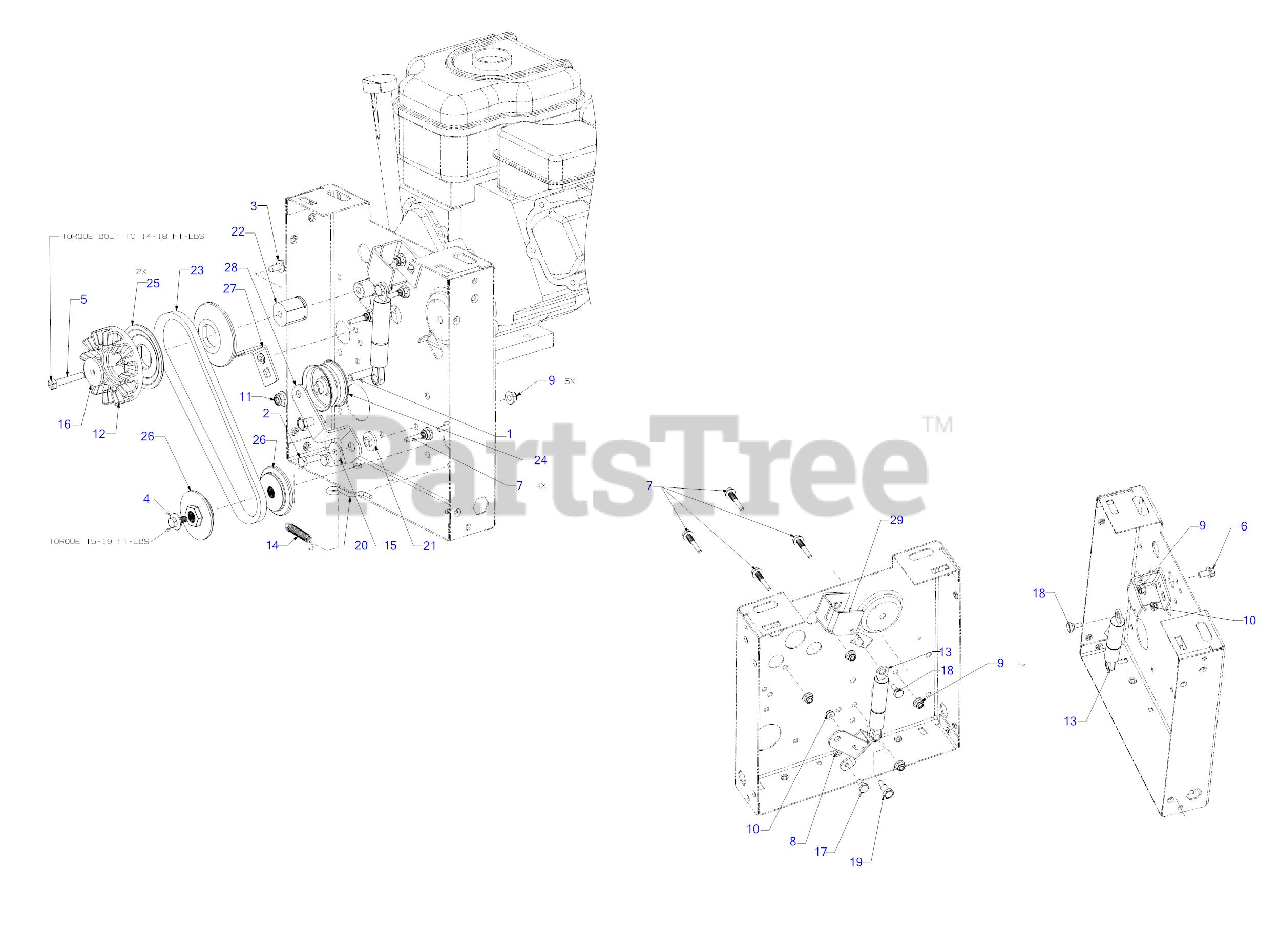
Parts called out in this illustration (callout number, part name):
1	HEX SCREW 3/8-16 x 1.75 GR5
2	SCREW 5/16-18 x 1.0 GR5
3	SCREW 5/16-18 x .750
4	SCREW 5/16-24 x .750 GR5
5	SCREW 5/16-24 x 1.88 GR8
6	SCREW 5/16-18 x .625 GR5
7	BELT KEEPER ROD .25 x 1.585
8	HEX NUT
9	FLANGE LOCK NUT 5/16-18
10	FLANGE LOCK NUT
12	DOG CLUTCH
13	DAMPER CYLINDER
14	EXTENSION SPRING 2.675"
15	FLAT WASHER 1.0 OD:.331 ID
16	FLAT WASHER
17	SHOULDER SCREW .340
18	SHOULDER SCREW
19	SHOULDER BOLT .395 DIA x .56 LG
21	SHOULDER SPACER
23	V-BELT 4L x 27
24	IDLER PULLEY
25	HALF PULLEY 3.4 DIA
26	HALF PULLEY 2.6 DIA
27	PTO CABLE BRACKET
28	DRIVE ACTUATOR IDLER BRACKET
29	DAMPENER CABLE BRACKET
